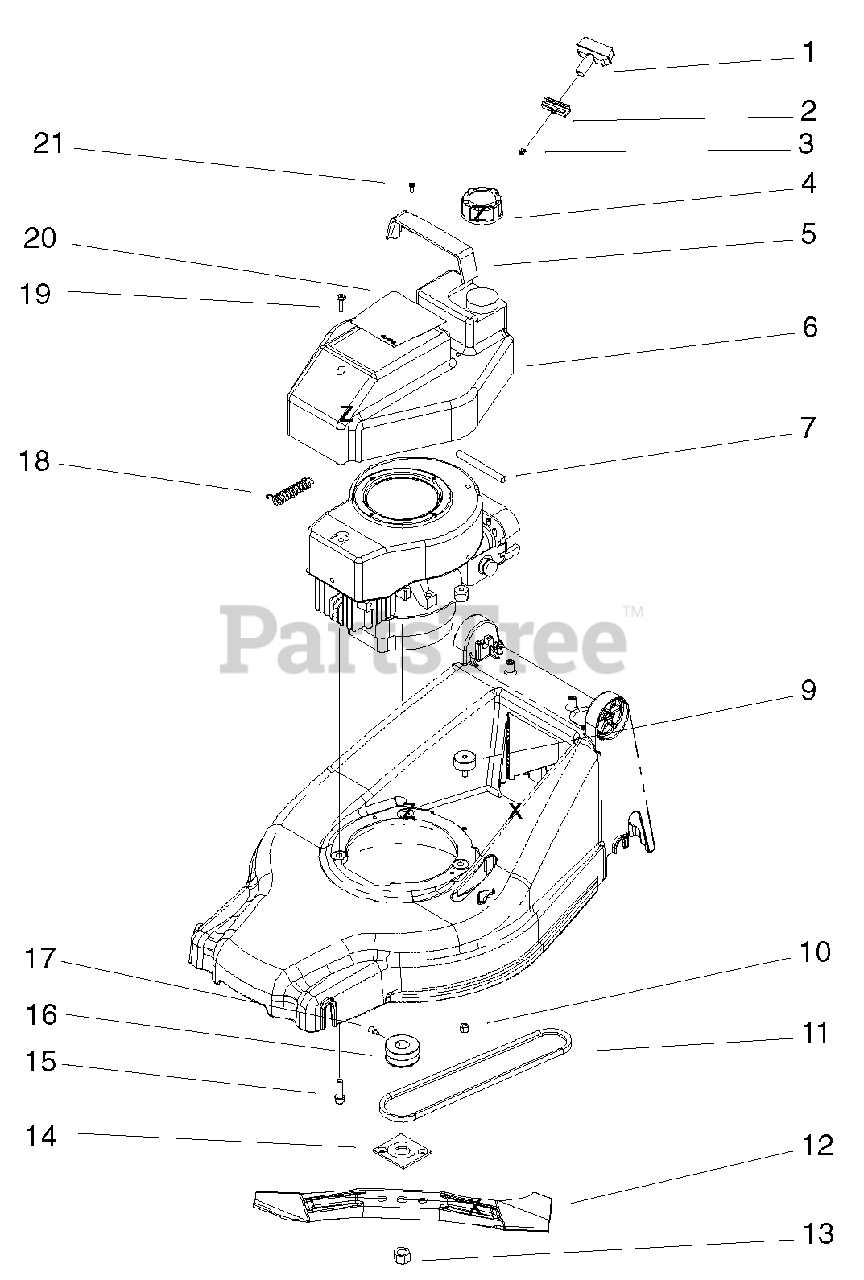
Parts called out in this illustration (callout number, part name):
1	Handle-Start
2	Starter-Clip
3	Rope-Stop
4	Gas Cap Assembly
5	Strap-Tank
6	Tank/Shroud
7	Fuel Line
9	Stud-Ball Bearing (only on: 10926)
10	Nut-Lock, NI (only on: 10926)
11	V-Belt (only on: 10926)
12	Blade
13	Nut-Blade
14	Plate & Collar ASM
15	Screw-Taptite w/Patch
16	Pulley (only on: 10926)
17	Screw-Set (only on: 10926)
18	Spring-Compression
20	Decal-Recoil
21	Screw-Phlps Pan Hd
